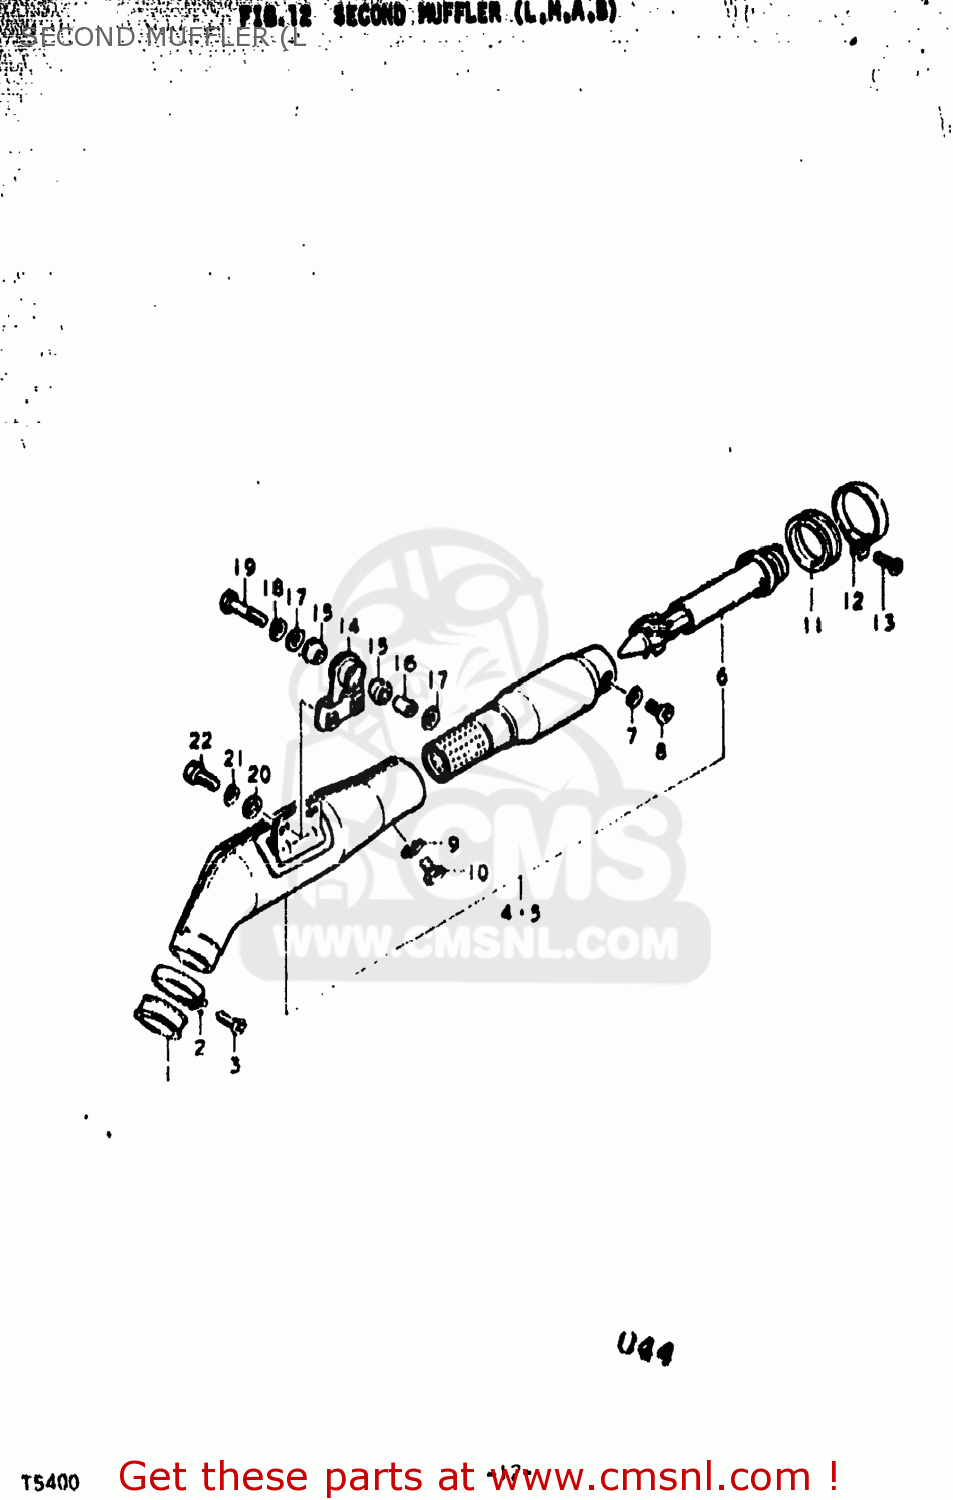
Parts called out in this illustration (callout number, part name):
1	CONNECTOR,MUFFLER
2	CLAMP
3	SCREW
4	MUFFLER ASSEMBLY
5	MUFFLER ASSEMBLY
6	TUBE,MUFFLER CLEAN OUT
7	LOCK WASHER
8	SCREW
9	LOCK WASHER
10	SCREW(6X8)
11	CONNECTOR,SECOND MUFFLER
12	CLAMP
13	SCREW
15	CUSHION
16	SPACER (8.2X12.5X23.5)
17	WASHER (8.7X22X2)
18	LOCK WASHER
19	BOLT 8X40
20	WASHER
21	LOCK WASHER
22	BOLT
